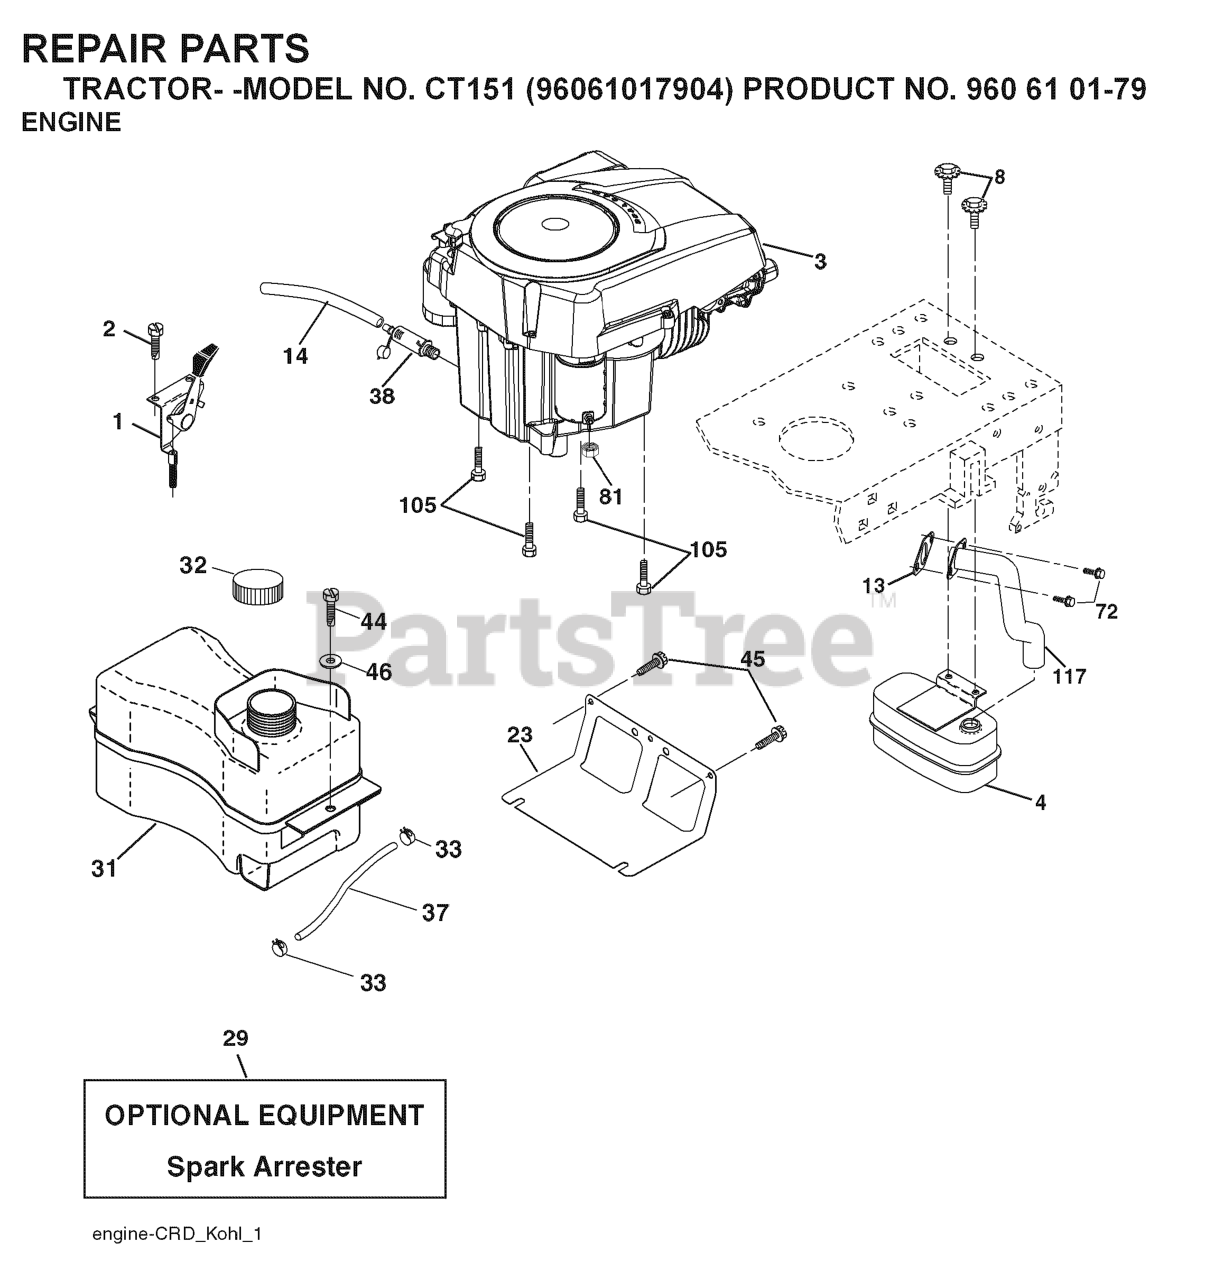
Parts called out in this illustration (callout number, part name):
1	CONTROL.TH/CK.C.
4	MUFFLER.SINGLE.CYL.KOHL/B&S
8	BOLT.5/16-18UNCX3/4 W/SEMS.BLK
13	GASKET.EXHAUST.KOHLER
14	TUBE, DRAIN OIL ASM.
23	SHIELD.BROWNING.DBR.GUARD
29	KIT.SPARK ARRESTOR 794945 B&S
31	RP TANK FUEL FRT 1.5 GAL
32	FUEL CAP
33	HOSE CLAMP
37	LINE.FUEL.20
38	PLUG DRAIN OIL EASY
44	SCREW HEXWSHR 1/4-20X3/4
45	SCREW, 3/8-16X3/4
72	SCREW.SOCKET HD.5/16-1
81	NUT
105	SCREW 3/8-16X1
117	RP.TUBE.EXHAUST.KOHL.COURAGE
